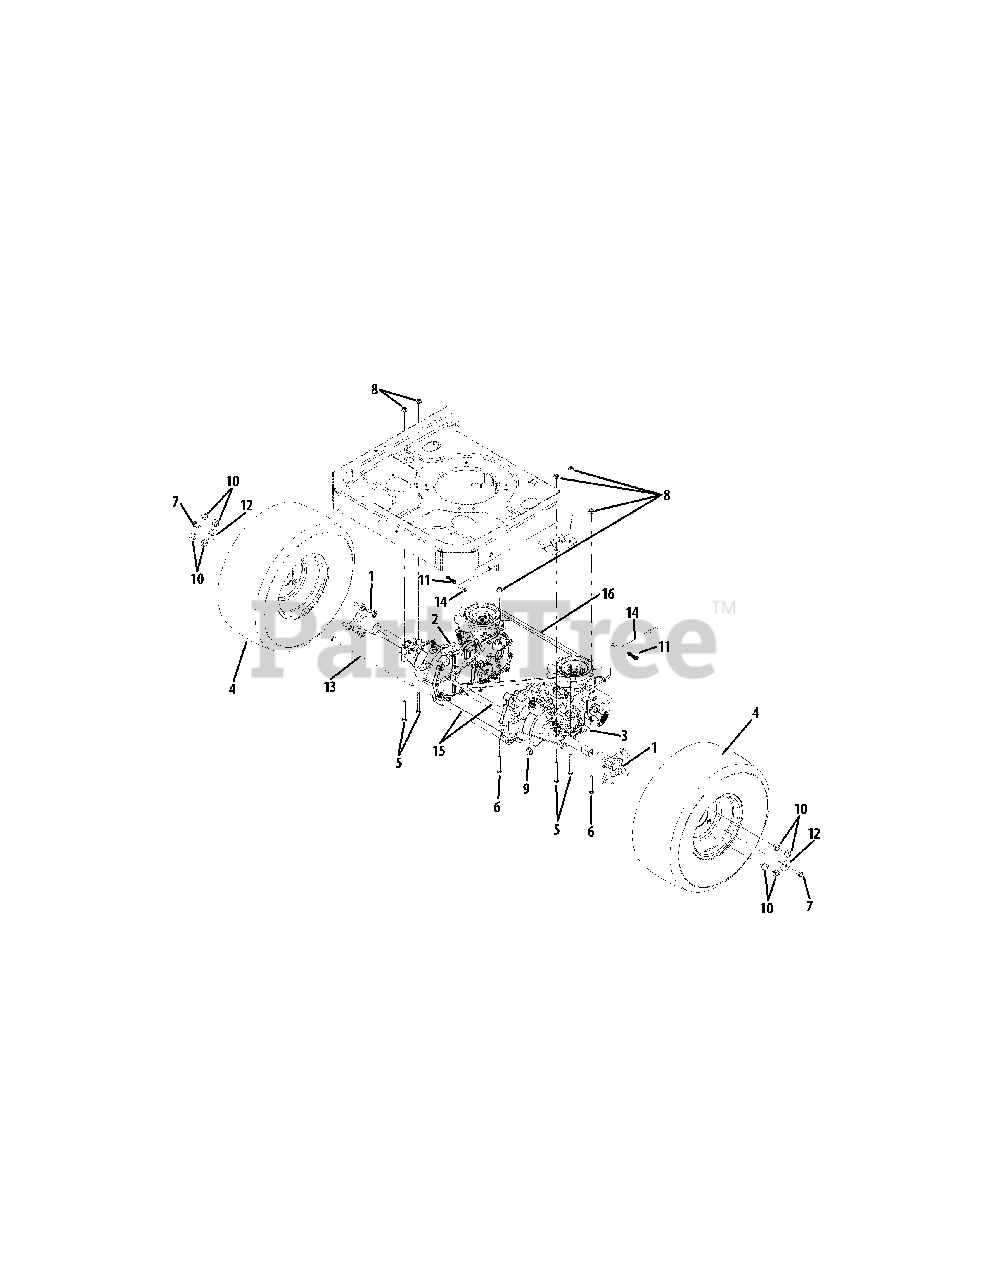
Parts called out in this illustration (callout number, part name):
1	Wheel Hub, 7/16-14 x 1.6
2	Transmission Assembly, LH
3	Transmission Assembly, RH
4	Wheel Assembly, 18 x 8.5-8 (42" Deck)
4	Wheel Assembly, 18 x 9.5-8 (50" Deck)
5	Hex Cap Screw, 5/16-18 x 2.75
6	Hex Cap Screw, 5/16-18 x 2.25
7	Hex Cap Screw, 3/8-16 x .75
8	Hex Flange Nut, 5/16-18
9	Hex Flange Nut, 7/16-20
10	Lug Nut, 7/16-14
11	Bow-Tie Cotter Pin
12	Flat Washer, .39 x 1.5 .134
13	Rod, .405 x 14.0
14	Bypass Rod
15	Tube, .45 x .69 x 10.2
16	V-Belt
